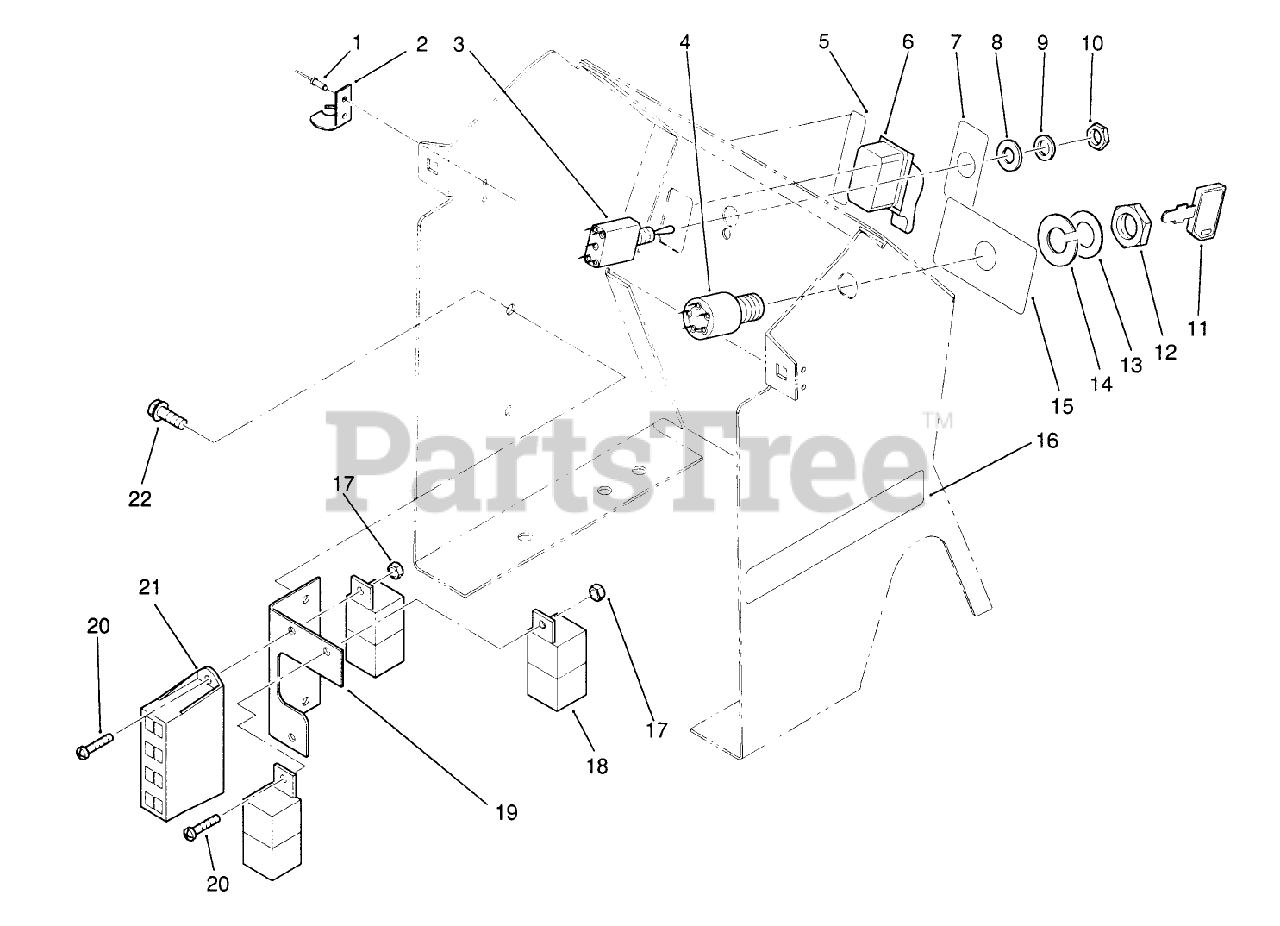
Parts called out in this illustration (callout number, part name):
2	KEEPER-LATCH
3	SWITCH-LIGHTS
4	KEY SWITCH ASM
6	PTO-SWITCH W/COVER
7	DECAL-LIGHTS
8	TAB-WASHER
9	Washer
10	*DISC**
18	RELAY
19	Bracket-Holder, Fuse
20	SCREW
